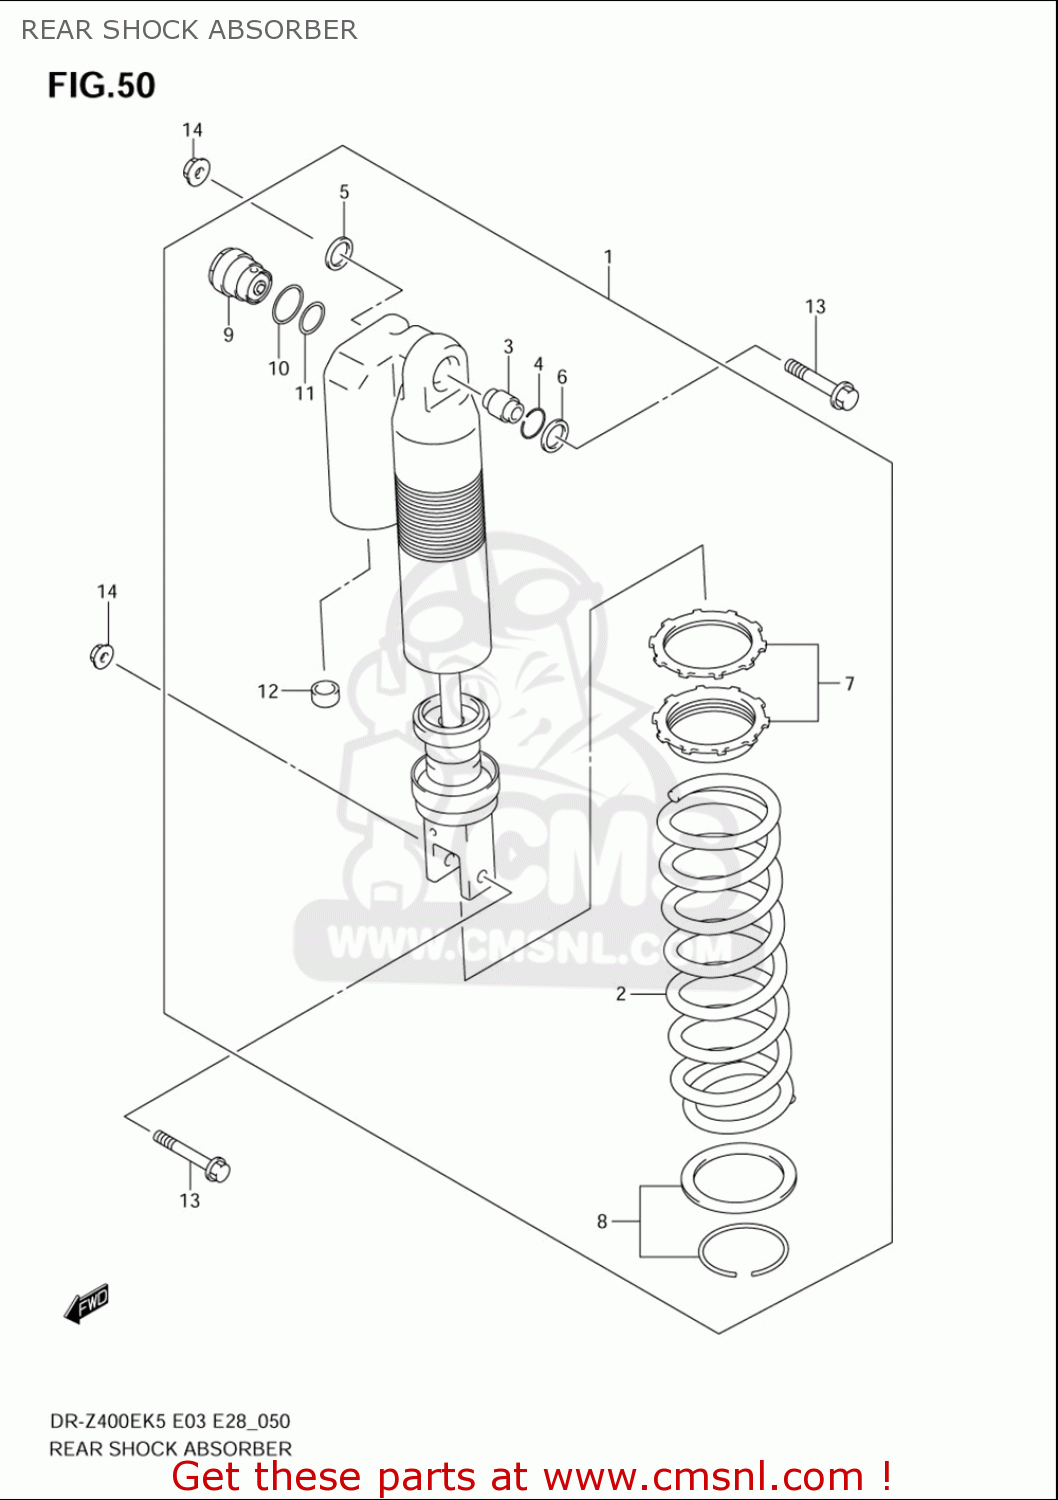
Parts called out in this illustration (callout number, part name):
1	ABSORBER ASSY,RR SHOCK
2	SPRING,RR(SOFT)
3	BEARING,RR SHOCK ABSORBER
4	RING,STOPPER
5	SEAL,DUST UPR,R
6	SEAL,DUST UPR,L
7	ADJUSTER SET
8	SPRING SEAT SET
9	BOLT,PLUG
10	O RING
11	O RING,CTR BOLT UPR
12	CAP,AIR VALVE
13	BOLT(10X47.5)
14	NUT
